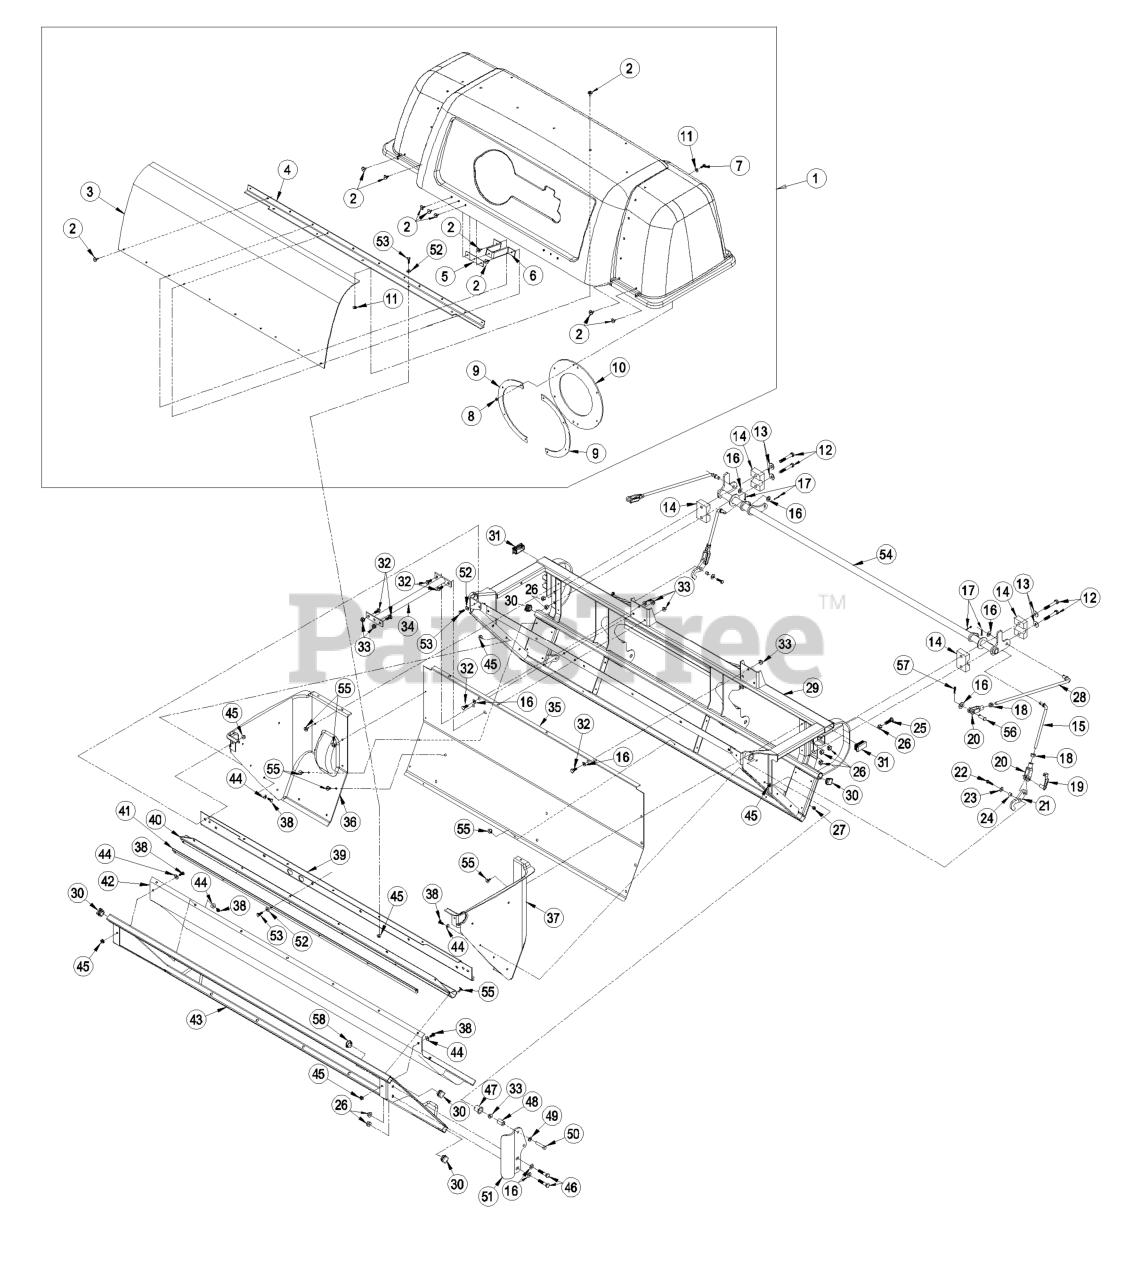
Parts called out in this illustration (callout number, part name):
1	ASM, HOOD - SERVICE ONLY
2	RIVET-BLIND
3	SCREEN-BAGGER
4	SUPPORT-SCREEN
5	PLATE-LATCH, REINFORCEMEN
6	BRACKET-MOUNT
7	SCREW-PPH
8	NUT-LOCK, NI
9	CLAMP-SEAL
10	SEAL-TUBE
11	WASHER-FLAT
12	BOLT-CARR
13	WASHER-FLAT
15	LINK-HANDLE
16	WASHER-FLAT
17	PIN-COTTER
18	NUT-HEX
19	PIN-SPRING, CLEVIS
20	YOKE-LINKAGE, BRAKE
22	SCREW-HH
23	WASHER-FLAT
25	SCREW-HH
26	NUT-HHF, WHIZ
27	NUT-LOCK, NI
28	LINK-HINGE
29	UPRIGHT-BAGGER
32	SCREW-HH
35	SHEET-WALL
36	PANEL-BAGGER, LH
37	PANEL-BAGGER, RH
38	SCREW-HH
39	REAR CROSSMEMBER ASM
40	SEAL-DOOR HINGE
41	STRAP-HOLD DOWN
42	BAG AND BOTTOM PANEL ASM
43	DOOR ASM
44	WASHER-FLAT
46	SCREW-HH
47	BUSHING
48	PIN-PIVOT, HINGE
49	WASHER-PLAIN
50	SCREW-HH
51	ARM-HINGE, LH
52	WASHER-FLAT
53	SCREW-HH
54	LINK-INTERMEDIATE
55	RIVET-BLIND
56	PIN-CLEVIS
57	PIN-COTTER
58	PLUG-DOME
